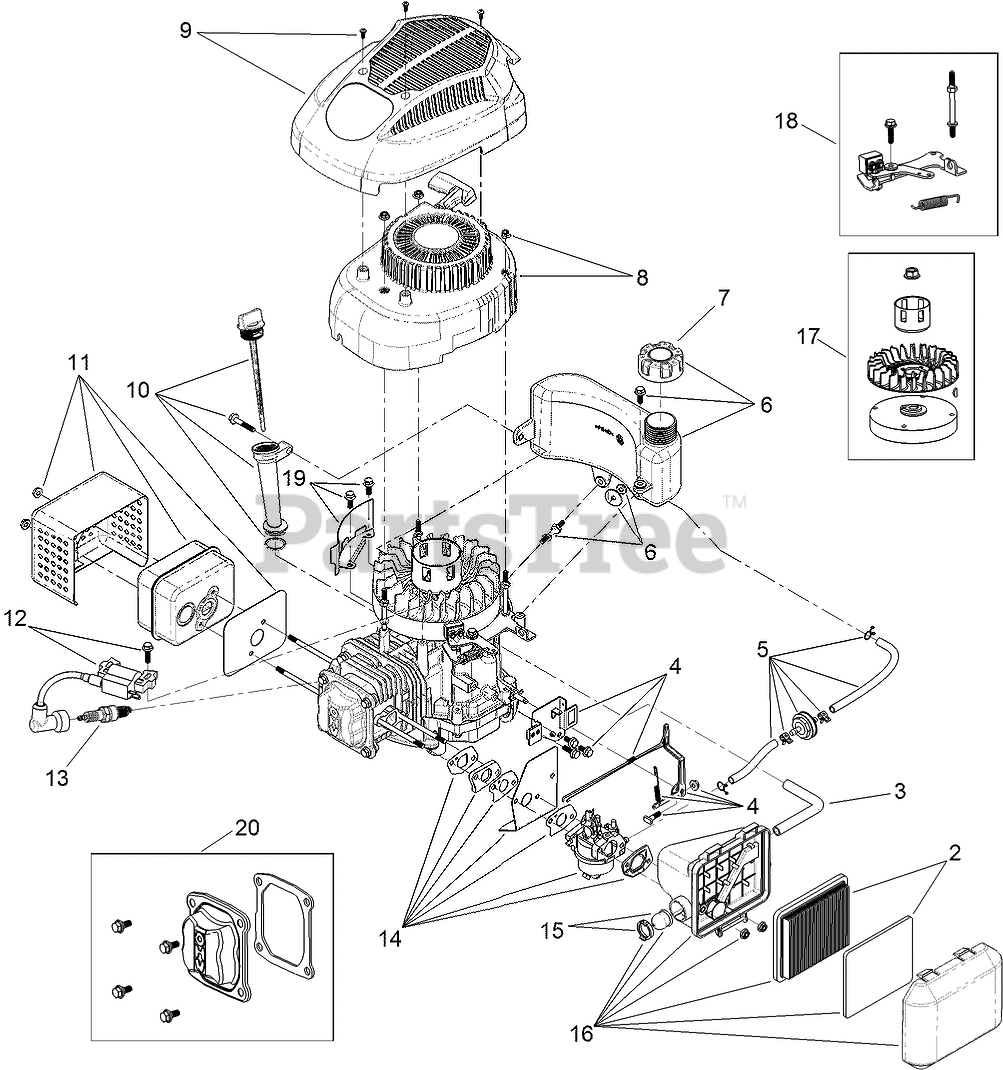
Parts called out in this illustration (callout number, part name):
2	AIR FILTER AND PREFILTER KIT
3	TUBE-BREATHER
4	GOVERNOR ARM KIT (SPRING AND LINK)
5	FUEL LINE KIT
6	FUEL TANK KIT (CAP AND HARDWARE)
7	CAP-FUEL
8	SHROUD AND RECOIL ASM
9	STYLING SHROUD KIT
10	DIPSTICK AND FILL TUBE KIT
11	MUFFLER KIT (HEAT SHIELD AND GASKETS)
12	IGNITION AND HARDWARE KIT
13	PLUG-SPARK
14	COMPLETE CARB SERVICE KIT
14	CARBURETOR REPAIR KIT
15	PRIMER BULB AND BASE KIT
16	KIT-AIR CLEANER ASM, PRIMER, 2 HINGE
17	FLYWHEEL AND FAN KIT
18	BRAKE ASM RECOIL KIT
19	FLYWHEEL SHIELD KIT
20	VALVE COVER KIT
